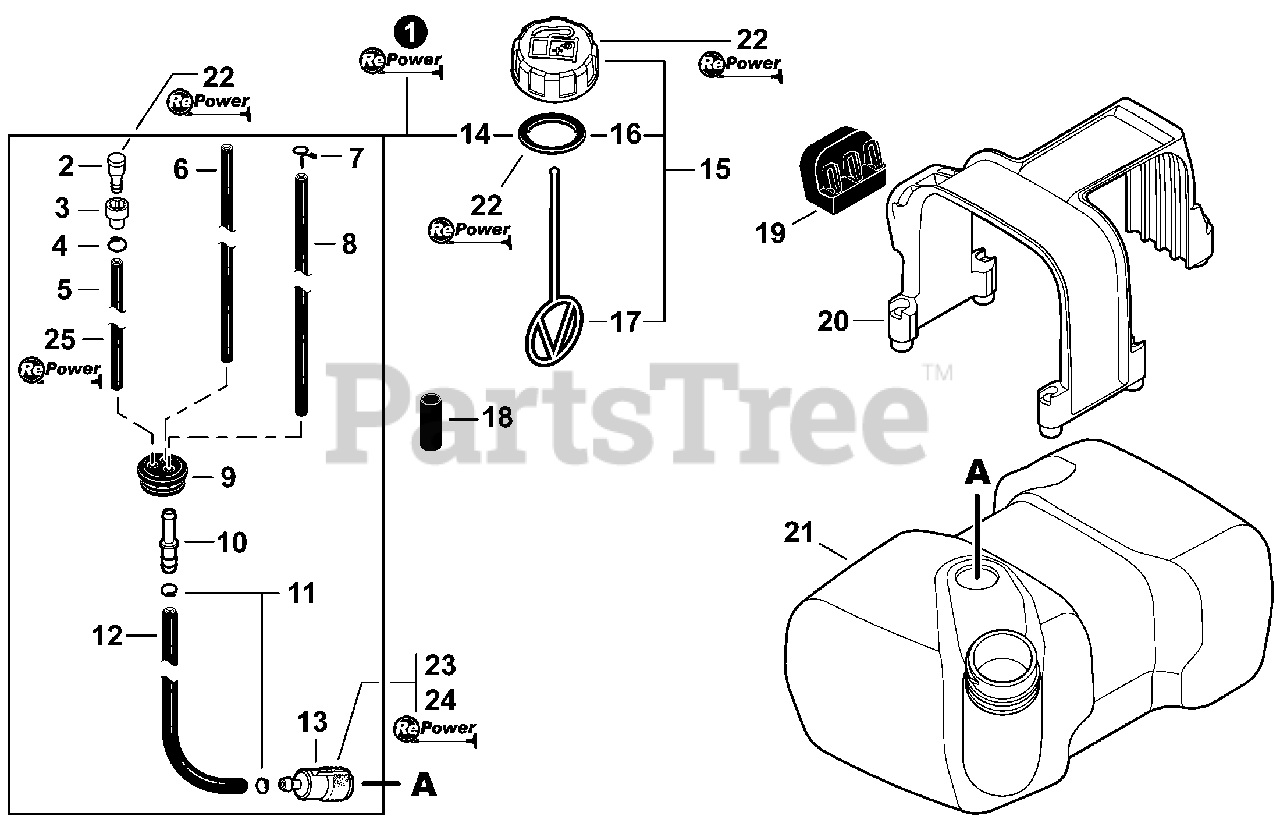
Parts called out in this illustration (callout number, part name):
1	FUEL SYSTEM KIT - REPOWER
2	VENT ASSY
3	HOLDER, VENT
4	CLIP Ø6.5MM
5	PIPE, FUEL VENT 3×6×130
6	PIPE, FUEL 2.4×5×200 BLACK
7	CLIP, SPRING Ø5.2
8	PIPE, FUEL 3×5×135L BLACK
9	GROMMET, FUEL
10	CONNECTOR, PIPE Ø5ר3.5
11	CLIP Ø6
12	PIPE, FUEL 3×5×105L BLACK
13	FILTER, FUEL
14	GASKET, FUEL CAP
15	CAP ASSY, FUEL
16	GASKET, FUEL CAP
17	CONNECTOR, CAP L= 100mm
18	TUBE, FUEL LINE 16×18×L40
19	CUSHION
20	RETAINER, FUEL TANK
21	TANK, FUEL
22	CAP/VENT KIT - REPOWER
23	TUNE-UP KIT - REPOWER
24	FILTER KIT - REPOWER
25	PIPE, BULK - 3×6mm BLACK
